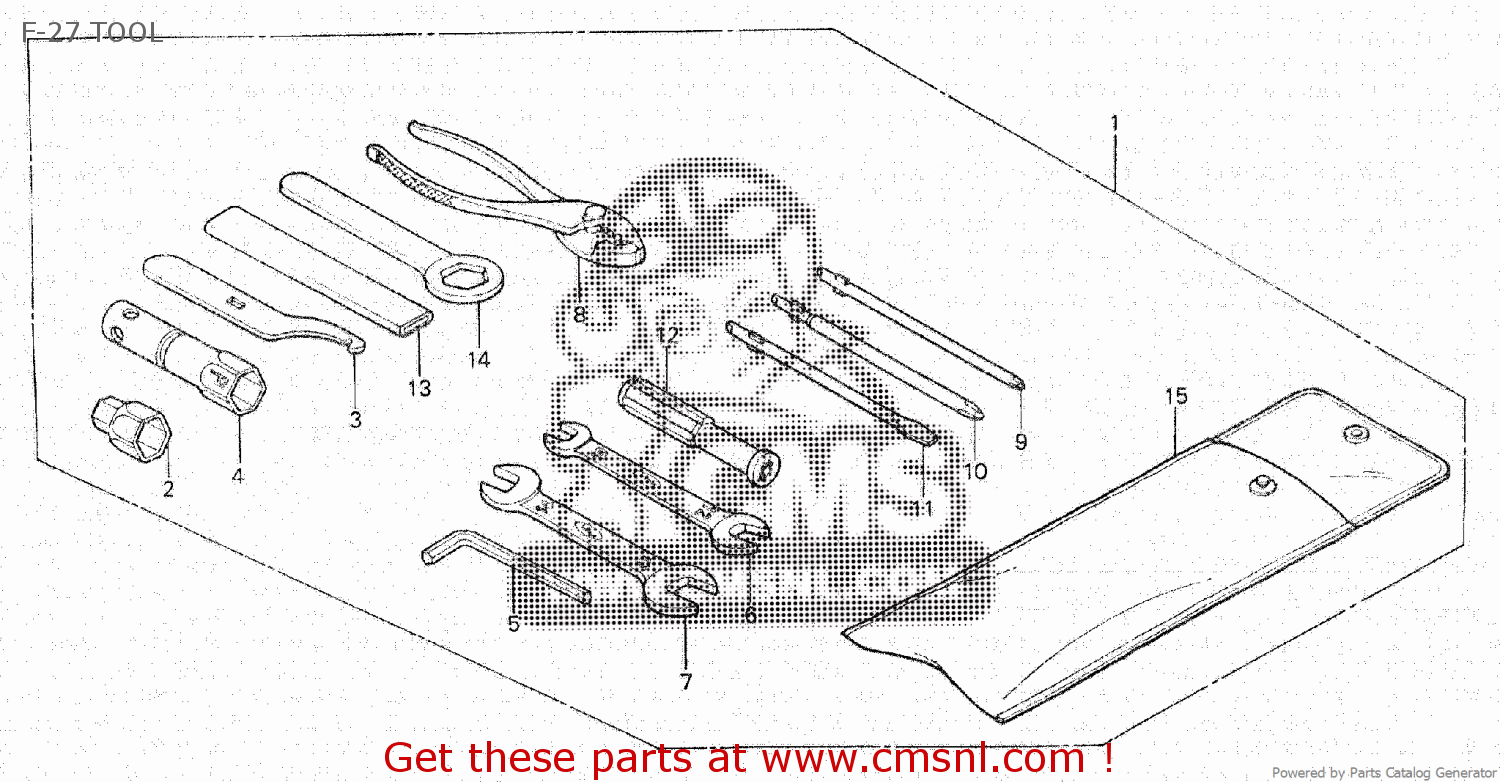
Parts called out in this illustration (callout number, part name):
1	TOOL ASSY
2	WRENCH BOX 22X17
3	SPANNER,PIN
4	WRENCH,PLUG
5	WRENCH,HEX.,5MM
6	SPANNER, 10X12
7	SPANNER, 14X17
8	PLIERS,135
9	DRIVER
10	DRIVER
11	SCREW DRIVER,3
12	GRIP,SCREW DRIVER
13	HANDLE,EYE WRENCH
14	EYE WRENCH,22
15	BAG,TOOL
